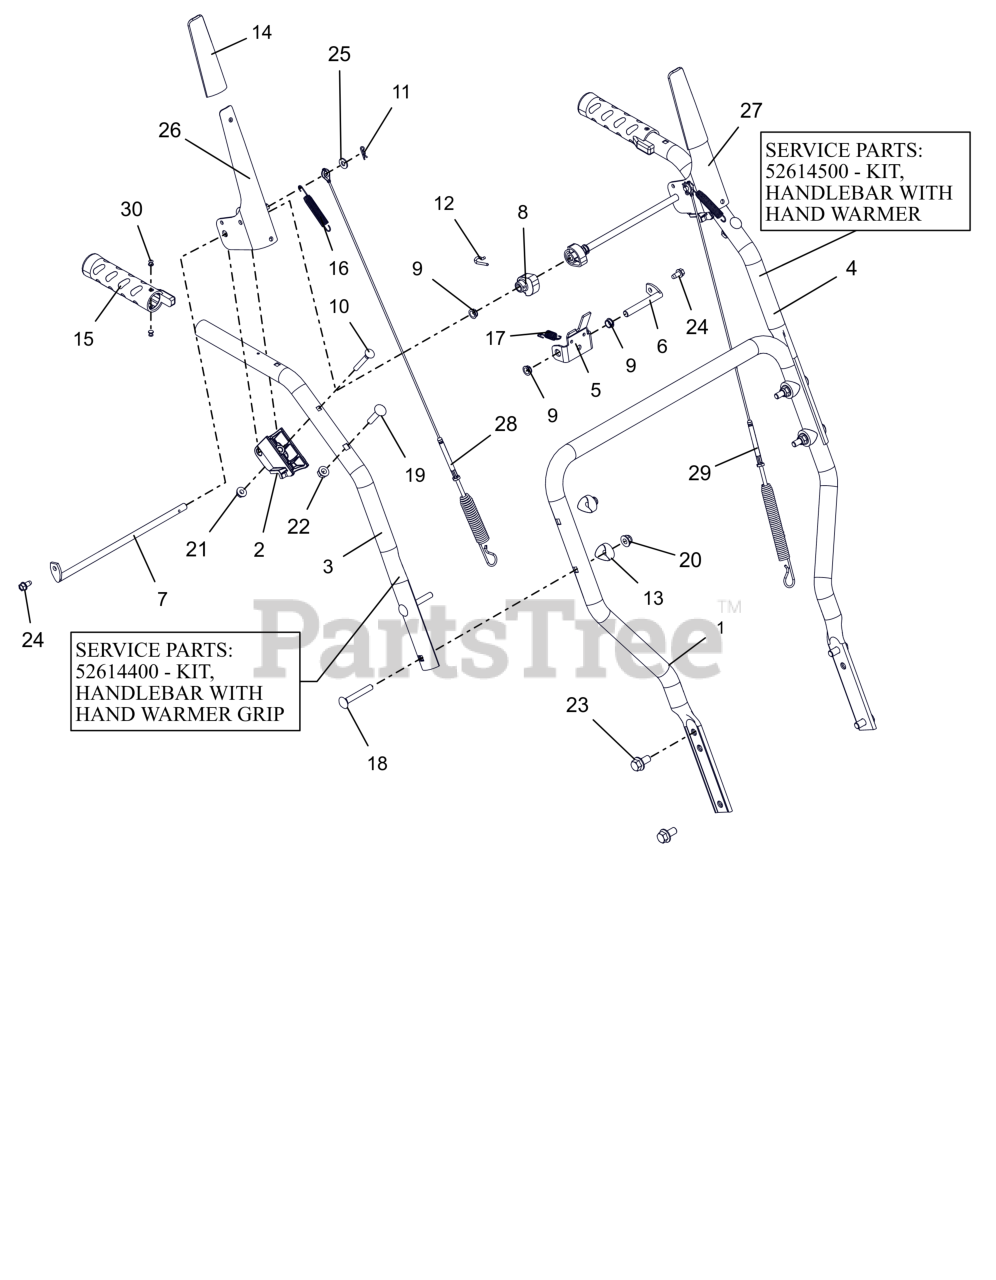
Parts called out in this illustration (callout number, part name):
1	HANDLEBAR, LOWER
2	BLOCK, CLUTCH PADDLE
3	HANDLEBAR, UPPER - RH
3	KIT, HANDLEBAR HW RH
4	HANDLEBAR, UPPER - LH
4	KIT, HANDLEBAR HW LH
5	BRACKET, INTERLOCK ARM
6	ROD, PIVOT - INTERLOCK
7	ROD, PADDLE MOUNT - PRO
8	CAM, INTERLOCK
9	BUSHING, POLYLINER-.38 SNAPIN
10	BLT-RDHDXLSQNK .25-20X2.0 G5YZ
11	PIN, HAIR #178 .06X.77 ZCC
12	PIN, SPRING CLIP
13	SPACER, HANDLEBAR
14	SLEEVE, CLUTCH PADDLE-GRAY
15	GRIP,HEATED HANDLE-GRAY
16	SPRING, EXTENSION
17	SPRING-EXT .047X.438X1.45
18	BLT, RHSN .31-18X2.25 G5 ZCC
19	BLT,RHSN .31-18X1.50 G5 ZCC
20	NUT,LK-NYL-FLG .31-18 G5ZC120
21	NUT-LK-CTR-FLG .25-20 ZC120
22	NUT-LK-TOP-FLG .312-18 GF ZCC
24	SCR-TAP .25-20X.50 HWH ZCC
25	WSHR,FLT .281X.625X.065 ZCC
26	LEVER, CLUTCH-RH
27	LEVER, CLUTCH-LH
28	CABLE, AUGER (DELUXE & PRO)
29	CABLE, UPPER TRACTION
30	RVT-POP #43 .125X.313 STL ZINC
